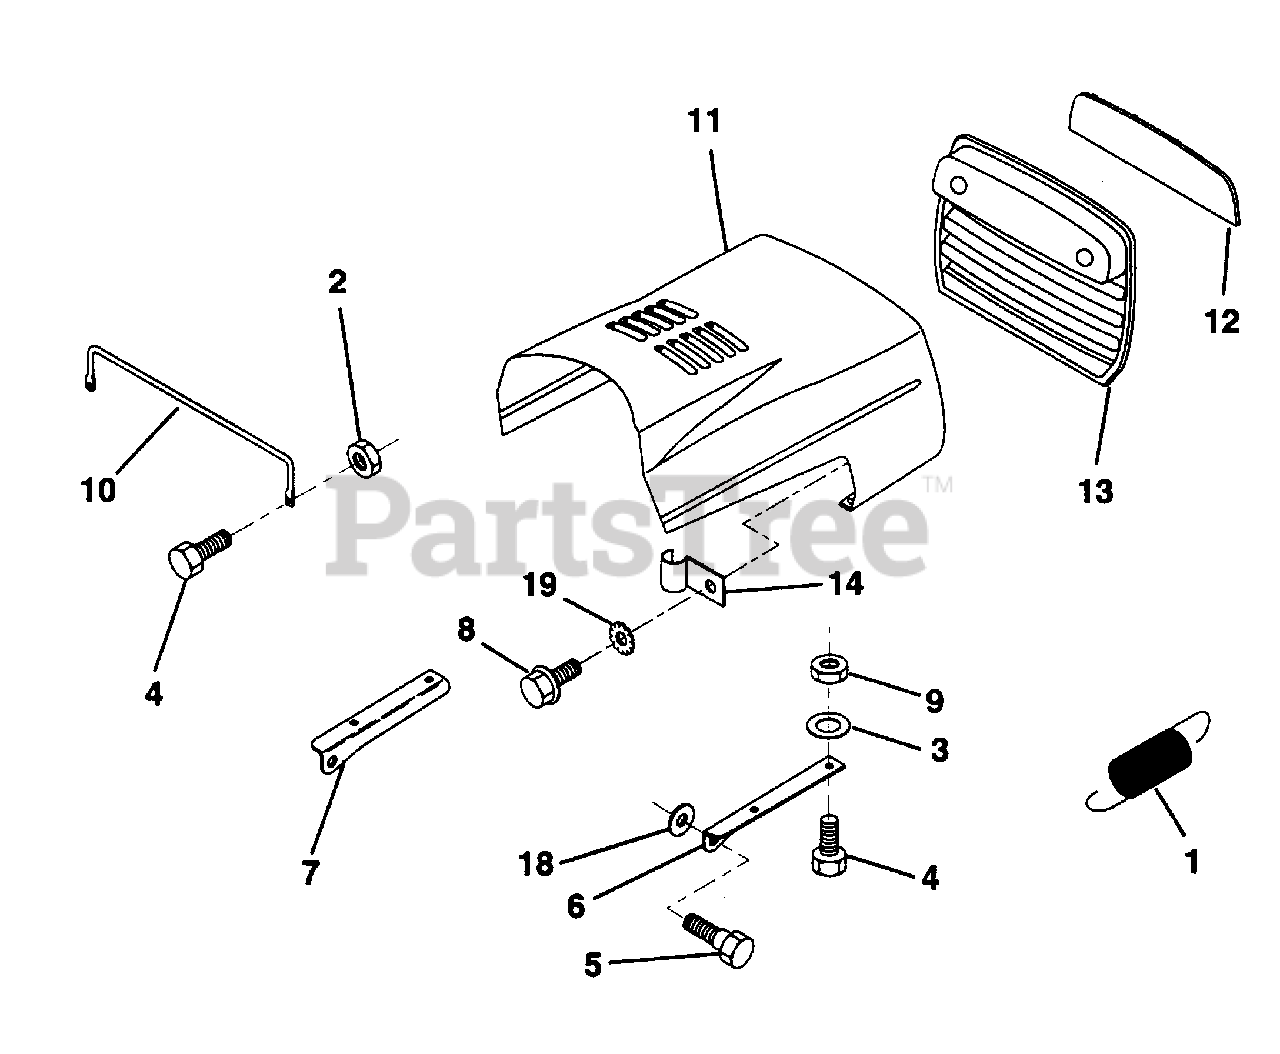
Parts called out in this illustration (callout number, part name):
1	Extension, Spring
2	Nut, Hex, Keps 1/4-20
3	Washer, 9/32 x 7/8 x 16 Ga.
4	Bolt, Hex Fin 1/4-20 x 3/4 Gr. 5
5	Bolt, Shoulder
6	Bracket, Hood R. H.
7	Bracket, Hood L.H.
8	Screw Sltd. Hex Hd W/PL Washer
9	Nut Lock W/Insert 1/4-20 UNC
12	Lens Clear Bar
14	Clip
18	Washer 11/32 x 11/16 x 16 Ga.
19	Washer Lock 1/4 Int/Ext Tooth
